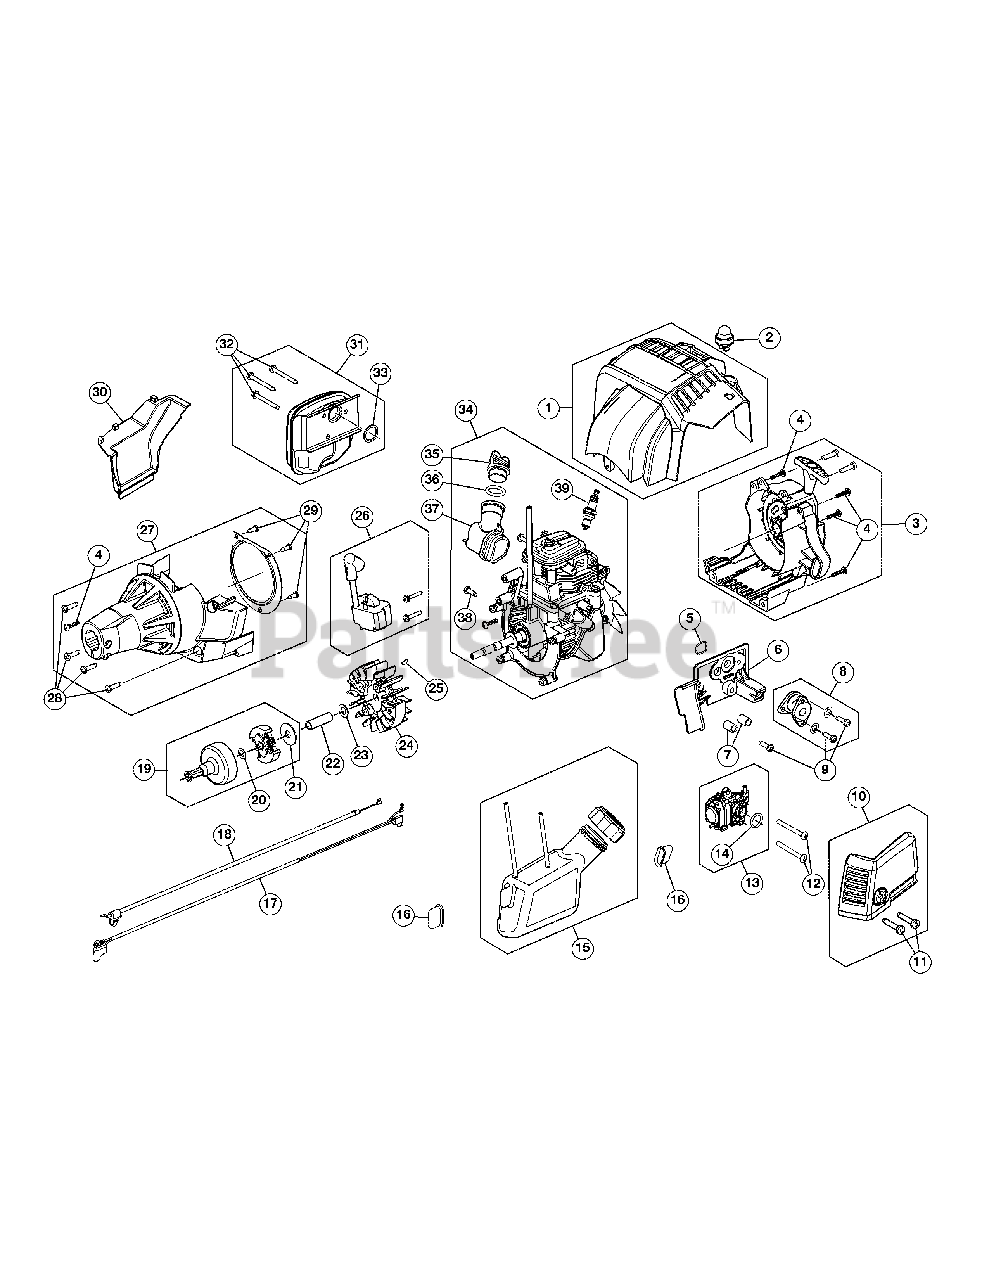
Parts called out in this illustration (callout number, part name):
1	Top Housing
2	Air Purge Primer
3	Starter Housing Assembly (Incl. 4)
5	O-Ring
6	Intake Port
7	Air Cleaner Spacer
8	Boot Assembly (Incl. 9)
9	Screw
10	Air Cleaner Assembly
13	Carburetor Assembly (Incl. 14)
15	Fuel Tank Assembly
16	Fuel Tank Pad
17	Lead Wire
18	Throttle Cable
19	Clutch Assembly (Incl. 20 & 21)
20	Thrust Washer
21	Clutch Washer
22	Spacer
23	Washer
24	Flywheel
26	Module Assembly
27	Clutch Cover Assembly
28	Screw
29	Screw
30	Rear Engine Cover
31	Muffler Assembly (Incl. 32 & 33)
33	Muffler Gasket
34	Shortblock Assembly (Incl. 35 - 39)
35	Oil Fill Plug
36	O-Ring
37	Oil Fill Tube
38	Screw
39	Spark Plug
